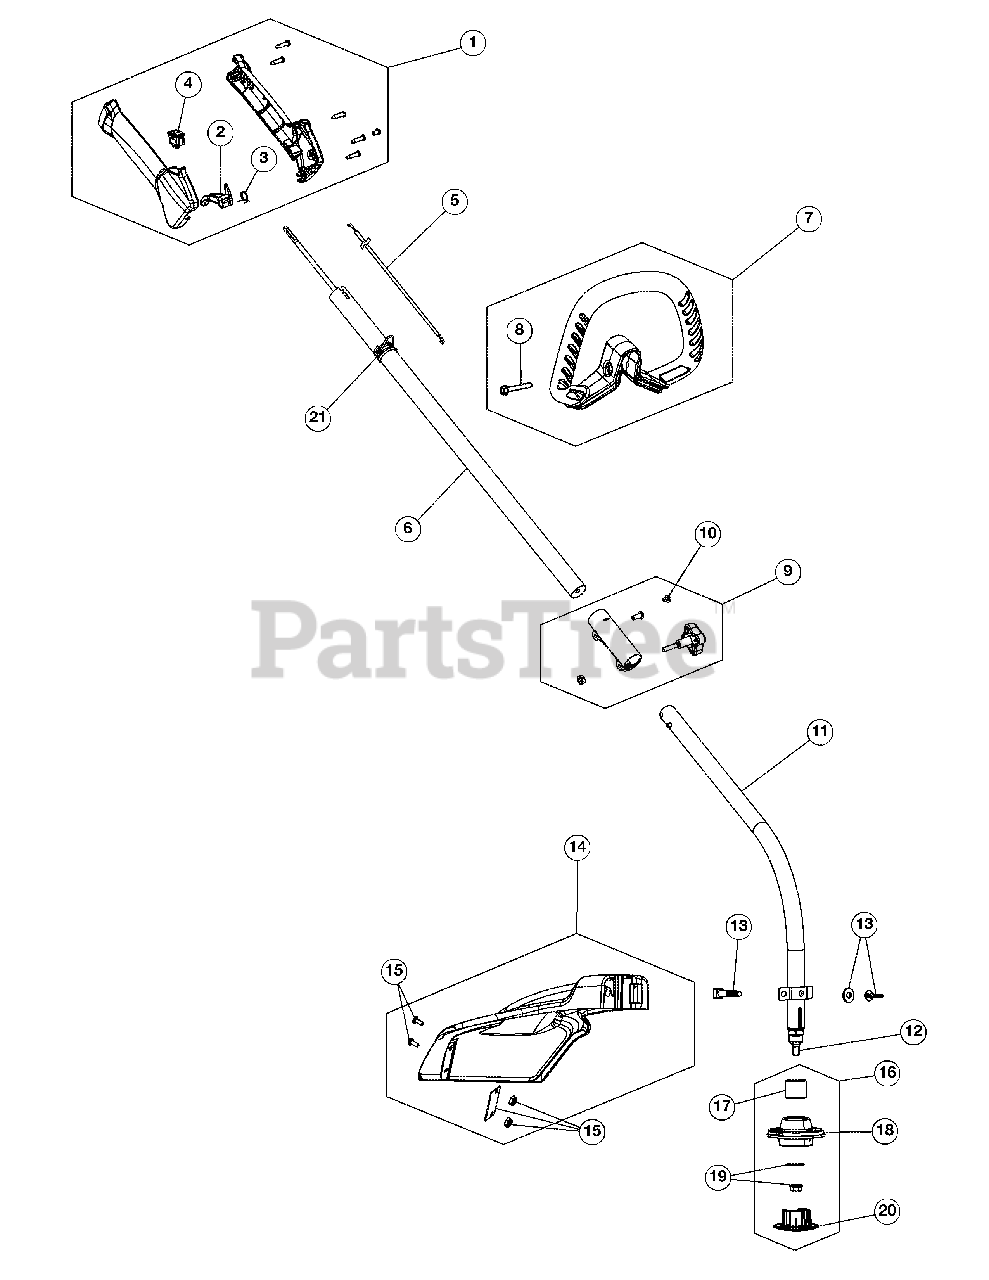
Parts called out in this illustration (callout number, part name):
1	Throttle Housing Assembly (Incl. 2-4)
2	Throttle Trigger
3	Throttle Trigger Spring
4	Switch Assembly
5	Throttle Cable Assembly
6	Upper Drive Shaft Assembly
7	D-Handle Assembly (Incl. 8)
9	Split Boom Coupler (Incl. 10)
10	Coupler Anti-Rotation Screw
11	Lower Drive Shaft Housing Assembly (Incl. 12)
12	Lower Flexible Drive Shaft Assembly
13	Shield Mount Hardware
14	Shield Assembly (Incl. 15)
15	Blade Assembly
16	Cutting Head Assembly (Incl. 17-20)
17	Weed Guard
18	Cutting Head Spool
19	Spool Mounting Hardware
20	Cutting Head Cap
21	Shoulder Strap Clip
